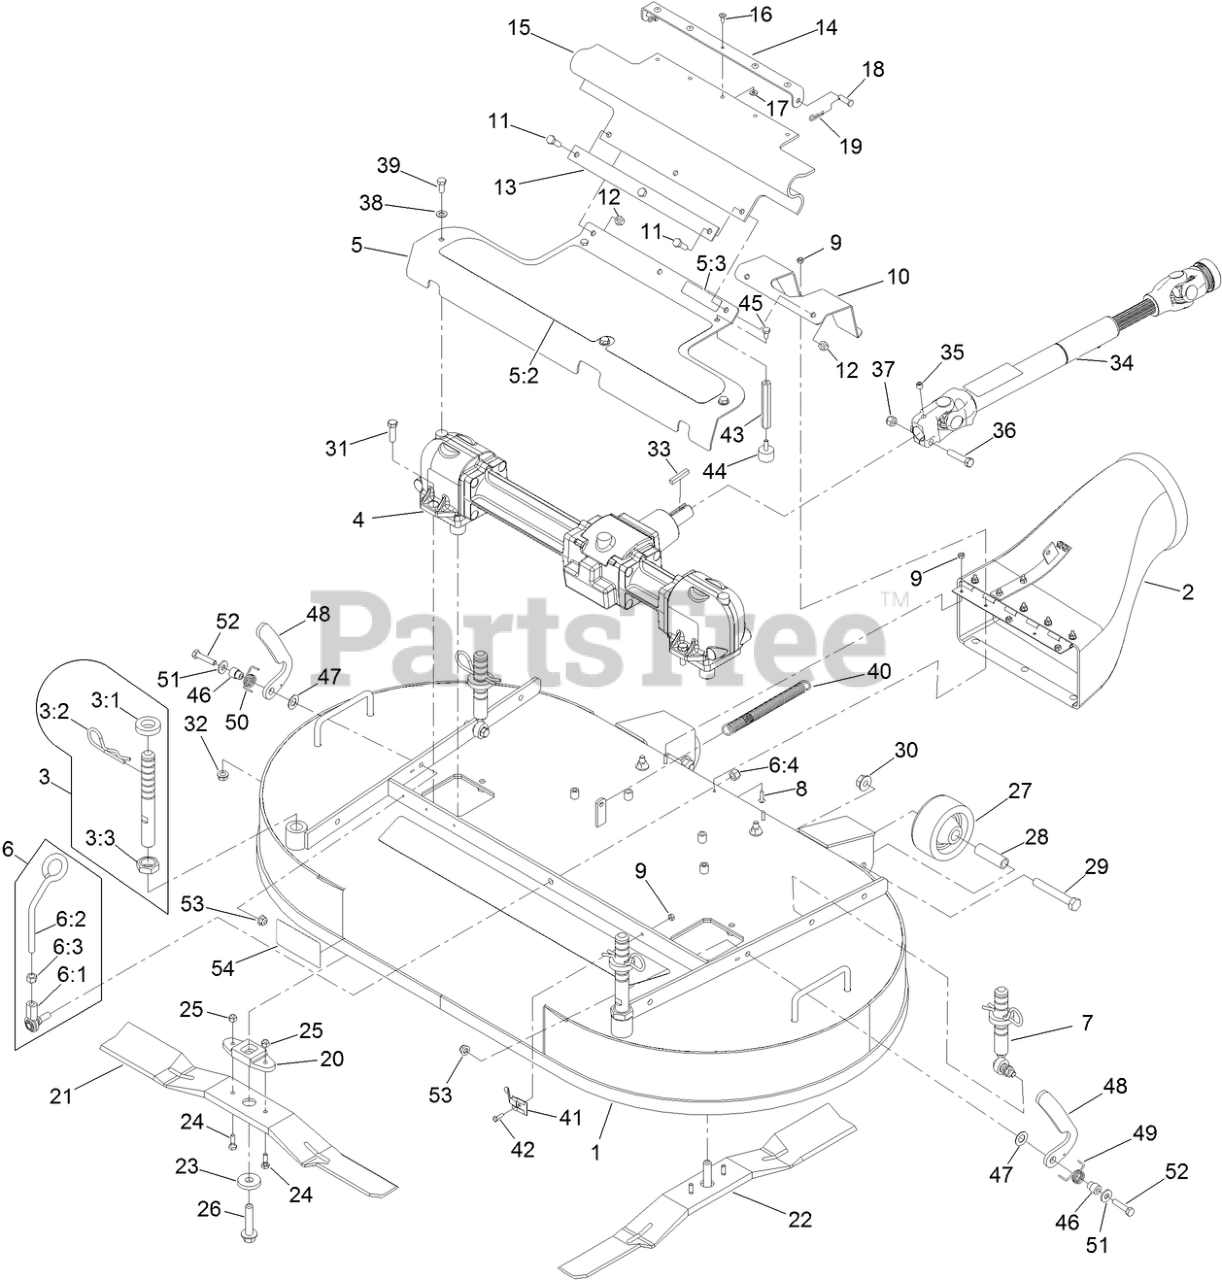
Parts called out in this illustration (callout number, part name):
1	DECK-CUTTING 48 W/DECALS
2	DISCHARGE TUBE ASM
3	FRONT DECK HEIGHT ADJUST ASM
3:1	SPACER-DECK SUPPORT
3:2	PIN-CUT HEIGHT
3:3	NUT-JAM
4	GEAR BOX ASM
5	GEARBOX COVER ASM
5:2	PAD-ANTI SKID
5:3	DECAL-DANGER
6	DECK LATCH ASM
6:1	BALLJOINT-RH
6:2	LATCH-DECK
6:3	NUT-HEX
6:4	NUT-LOCK
7	REAR DECK HEIGHT ADJUST ASM
8	SCREW-HEAD, TRUSS
9	NUT-LOCK, NI
10	GUARD-DRIVE SHAFT
11	SCREW-HH
12	NUT-LOCK, NI
13	STRAP-DRIVE, LINE COVER
14	BRACKET-GUARD, PTO
15	GUARD-PTO
16	RIVET-BLIND
17	WASHER-FLAT
18	PIN-CLEVIS
19	PIN-COTTER
20	DRIVER-BLADE
21	BLADE-25IN, RH
22	BLADE-25IN, LH
23	WASHER
24	BOLT-SHEAR
25	NUT-LOCK, NI
26	BOLT-BLADE
27	ROLLER-DECK
28	SPACER-ROLLER
29	SCREW-HH
30	NUT-HHF
31	SCREW-HH
32	NUT-HHF, WHIZ
33	KEY-SQUARE
34	DRIVE SHAFT ASM
35	SCREW-SET, HSH
36	SCREW-HH
37	NUT-LOCK, NI
38	WASHER-PLAIN
39	SCREW-HH
40	SPRING-EXTENSION
41	CLIP-DECK, HOLD UP ROD
43	STAND-OFF
44	BUMPER
45	SCREW-HH
46	COLLAR-BASKET
47	WASHER-PLASTIC
48	LATCH - DECK
49	SPRING-TORSION, LH (YELLOW)
50	SPRING-TORSION, RH
51	WASHER-FLAT
52	SCREW-HH
53	NUT-HF, NI
